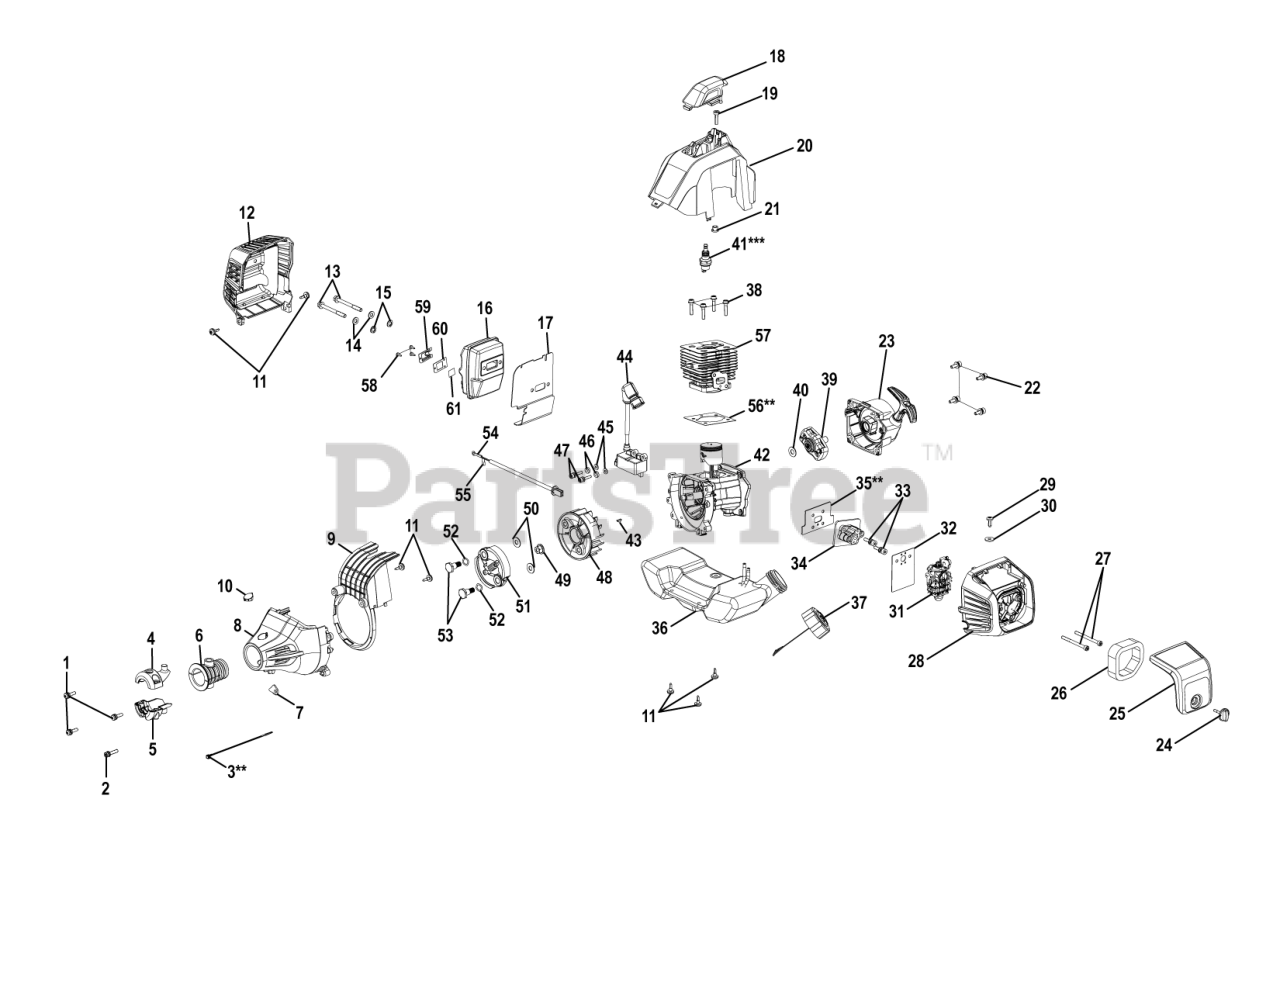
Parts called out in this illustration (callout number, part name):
3	Cable Tie
4	CLAMP, CLUTCH HOUSING TOP
5	CLAMP, CLUTCH HOUSING LOWER
6	SLEEVE, CLUCH HOUSING
7	CLIP, THROTTLE CABLE RETAINING
8	ASSY., CLUTCH HOUSING
9	PLATE, BAFFLE
10	PLUG, FRONT CLUTCH HOUSING
11	SCREW, SHOULDER
12	COVER, MUFFLER
15	WASHER, LOCK
16	ASSY., MUFFLER
17	GASKET, MUFFLER
18	COVER, SPARK PLUG
19	SCREW, CAP
20	HOUSING, TOP
21	BUSHING, TOP
23	ASSY., STARTER W/LABEL
24	KNOB, CARBURETOR COVER
25	COVER W/KNOB, AIRBOX
26	FILTER, AIR
28	BASE W/ CHOKE LABEL, AIRBOX
30	WASHER, RETAINING
31	ASSY., CARBURETOR
32	GASKET, CARBURETOR
34	DAM, HEAT
35	GASKET, HEAT DAM
36	ASSY., FUEL TANK W/CAP
37	ASSY., FUEL CAP
39	ASSY., STARTER PAWL AND PULLEY
41	PLUG, SPARK
42	ASSY., SHORT BLOCK
43	KEY, FLYWHEEL
44	MODULE, IGNITION
48	FLYWHEEL
49	NUT, HEX FLANGE
51	ASSY., CLUTCH
52	WASHER, CURVED
53	SCREW, CLUTCH
54	WIRE, LEAD (BLACK)
55	WIRE, LEAD (RED)
56	GASKET, CYLINDER
57	CYLINDER
59	PLATE, OUTLET
60	PLATE, INNER
61	ARRESTOR, SPARK
